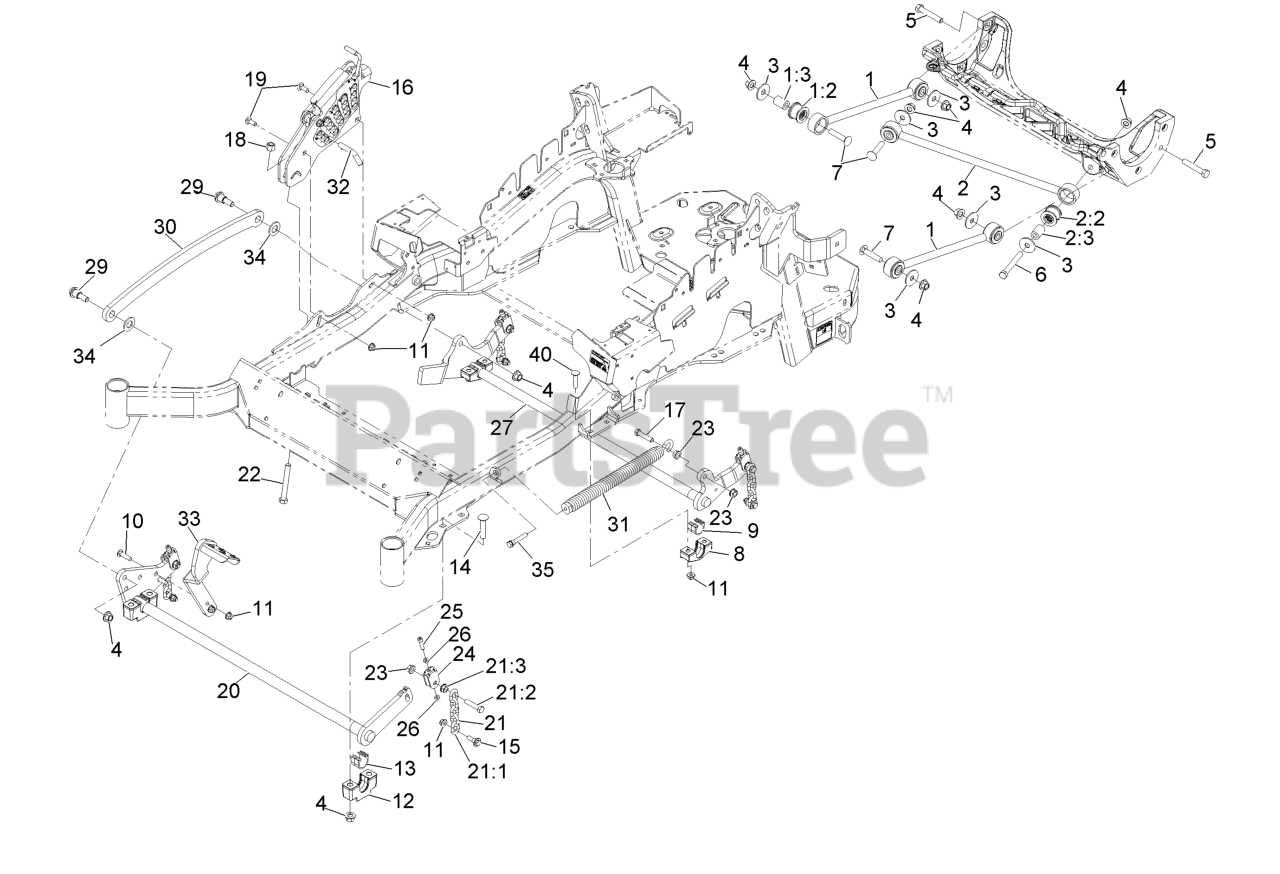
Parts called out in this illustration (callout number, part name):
1	LONG STRUT ASM
1:2	BUSHING-SUSPENSION, RUBBER
2	PANHARD ROD ASM
2:2	BUSHING-SUSPENSION, RUBBER
3	WASHER-THRUST
4	Nut-Lock 1/2-13
5	SCREW-HH
6	SCREW-HH
7	SCREW-CARR
9	BEARING-CROSS SHAFT, REAR
10	SCREW-CARR
11	NUT-HF, NI
12	SUPPORT-CROSS SHAFT, BEARING
13	BEARING-CROSS SHAFT, FRON
14	Bolt-Carriage 1/2-13 X 2 1/2 Spl Neck
15	SCREW-SHOULDER, HHF
16	HOC ASM
17	SCREW-HH
18	NUT-LOCK, NI
19	BOLT-CARR
21	DECK LIFT CHAIN ASM
21:1	CHAIN-LIFT, DECK
21:2	SCREW-HH
22	BOLT-TAP
24	YOKE-ADJUST, DECK
25	SCREW-HSH
26	NUT-JAM
27	LIFT-DECK, REAR
29	SCREW-SHOULDER, HHF 1/2-13 X 1.12
30	LINK-LIFT, DECK
31	SPRING-EXTENSION
32	PIN-HOC
33	LEVER-FOOT
34	WASHER-FLAT
35	BOLT-SHOULDER
40	SCREW-CARR
